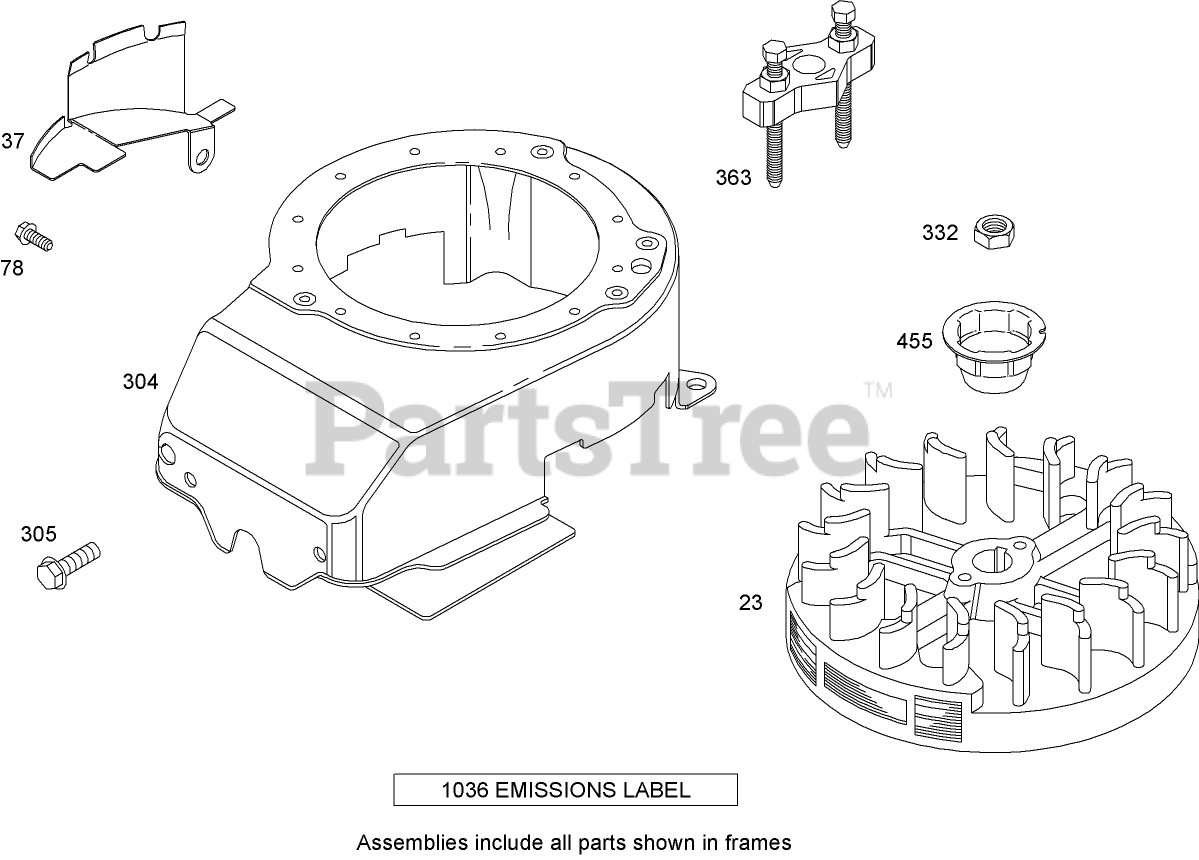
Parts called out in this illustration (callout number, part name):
23	Flywheel
37	Guard-Flywheel
78	Screw
304	Housing-Blower
305	Screw
332	Nut
363	Puller-Flywheel
455	Cup-Flywheel
1036	Loose Parts Package
